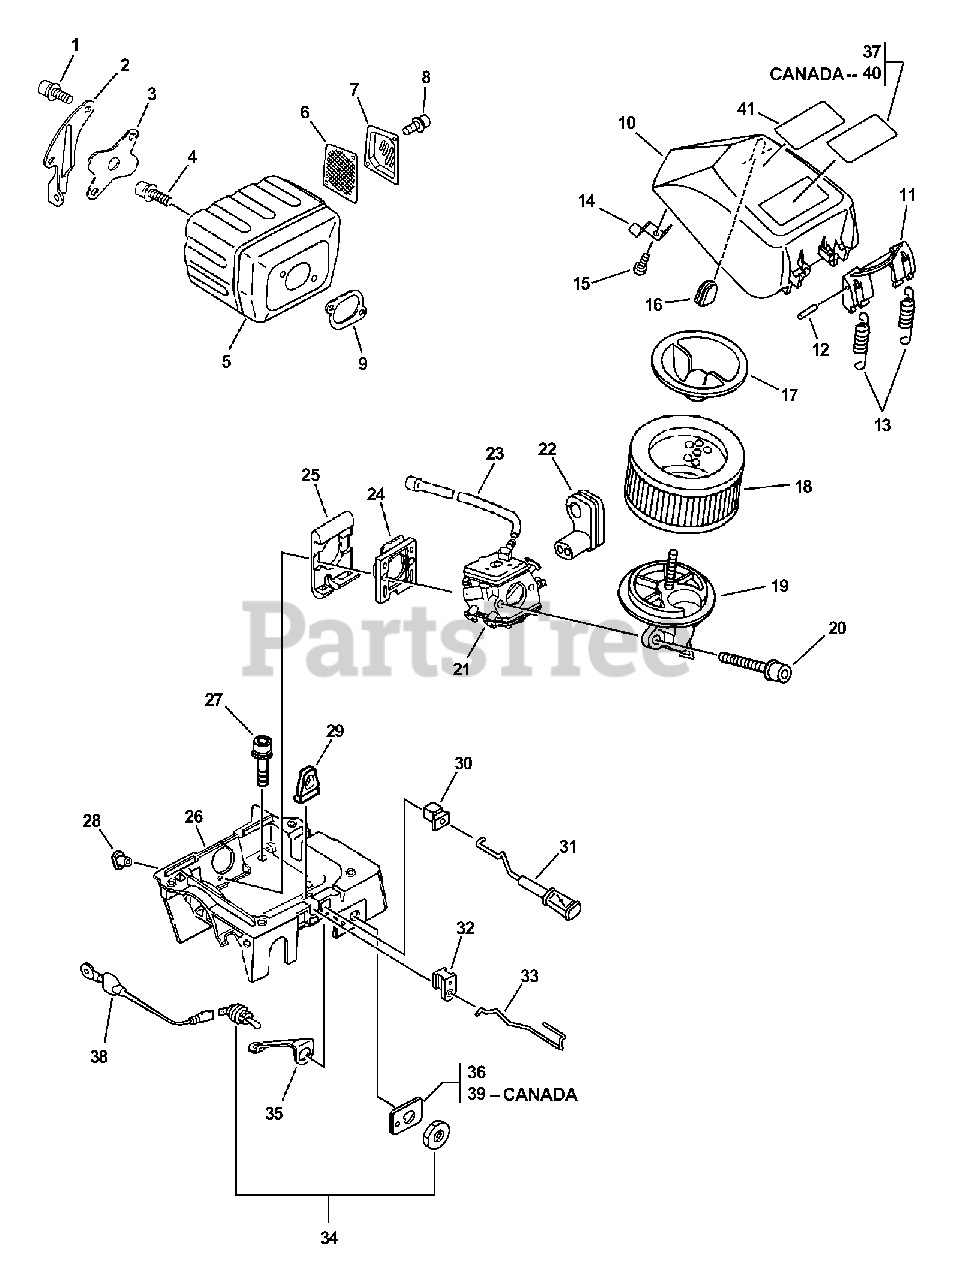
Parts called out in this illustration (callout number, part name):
1	BOLT 5×14
2	BRACKET, MUFFLER
3	COVER, MUFFLER
4	BOLT 5×20
5	MUFFLER
6	SCREEN, SPARK ARRESTER
7	GUIDE, EXHAUST
8	BOLT 4×10
9	GASKET, EXHAUST
10	LATCH, FILTER COVER
11	COVER, AIR FILTER
12	PIN 3×12
13	SPRING, TENSION
14	SPRING, FLAT
15	SCREW 4×10
17	COVER, AIR FILTER
18	FILTER, AIR
19	MOUNT, AIR FILTER
20	BOLT, FLANGE
21	CARBURETOR
22	GROMMET, NEEDLE
23	PIPE, IMPULSE
24	INSULATOR, INTAKE
25	CUSHION
26	CASE, CARBURETOR
27	BOLT 5×20
29	CUSHION
30	GROMMET, CHOKE
31	ROD, CHOKE
32	GROMMET, THROTTLE ROD
33	ROD, THROTTLE
34	SWITCH, ON-OFF
35	PLATE, GROUND
36	LABEL, STOP
37	LABEL, MODEL
38	LEAD
39	LABEL, STOP
40	LABEL, MODEL
41	LABEL, ATTENTION - CANADA
